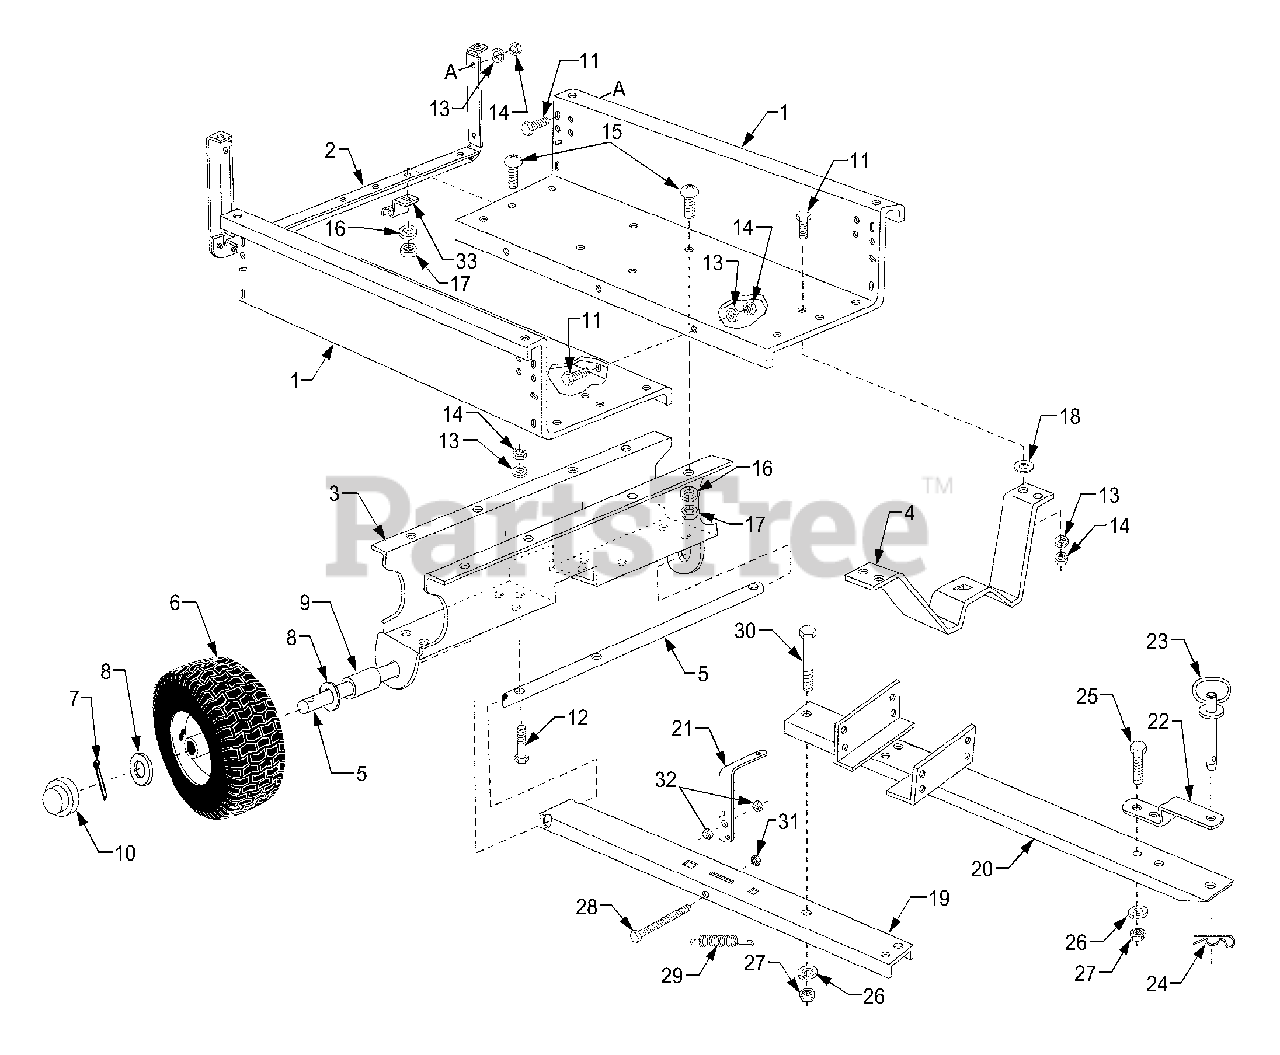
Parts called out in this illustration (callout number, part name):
7	Cotter Pin,1/8"Dia.x 1-1/2"
8	Washer,Flat 1"
9	Spacer Tube,1-1/4"x 2"Lg
10	Hub Cap
11	Hex Bolt,1/4-20 x 5/8"
12	Hex Bolt,1/4-20 x 1-3/4"
13	Lockwasher,1/4"
14	Hex Nut,1/4-20 Thread
15	Truss Hd.Bolt,5/16-18 x 3/4"
16	Lockwasher,5/16"
17	Hex Nut,5/16-18 Thread
18	Washer,Flat 1/4"
19	Tongue Weldment Ass'y.(Rear)
20	Tongue Weldment Ass'y.(Front)
21	Latch Lock Lever
22	Hitch Bracket
23	Hitch Pin
24	Pin,Hair Cotter 1/8"
25	Hex Bolt,3/8-16 x 1-1/4"
26	Lockwasher,3/8"
27	Hex Lock Nut,3/8-16 Thread
28	Hex Bolt,5/16-18 x 3-3/4"
29	Spring,Extension
30	Hex Bolt,3/8-16 x 3"
31	Hex Lock Nut,5/16-18
32	Hex Nut,5/16-18 (SIMS)
33	Door Support
